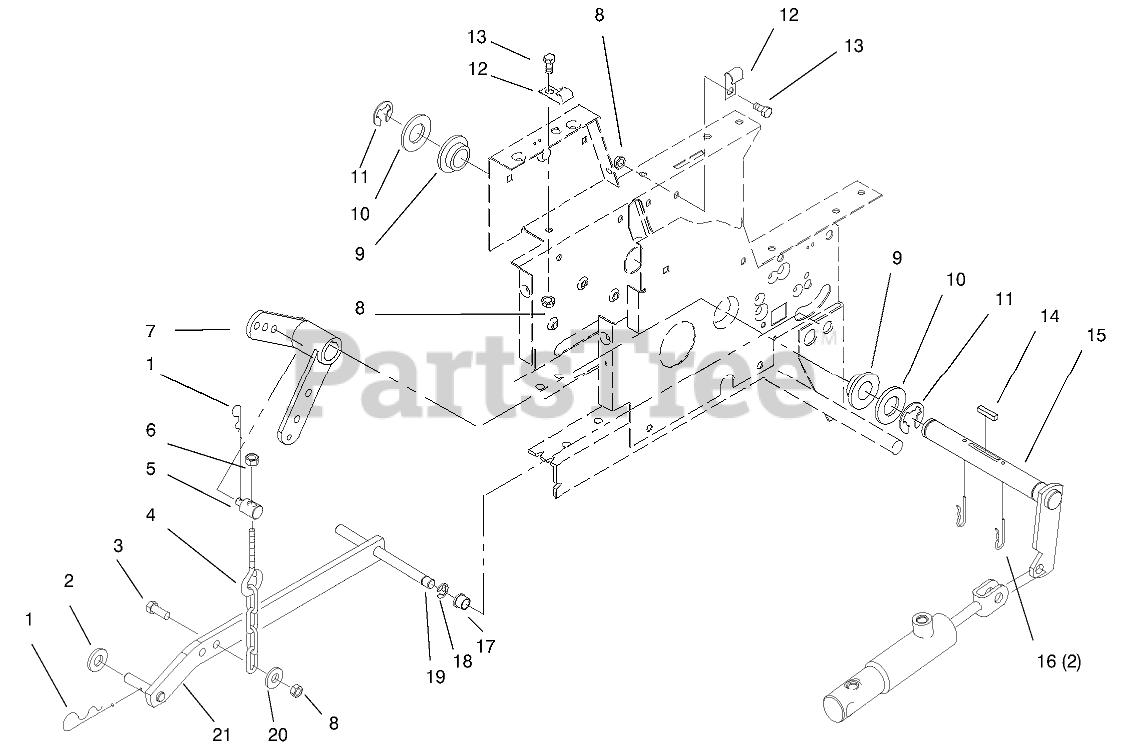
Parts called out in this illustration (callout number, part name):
1	PIN-HAIR
2	WASHER-FLAT
3	SCREW-HH
4	CHAIN-LIFT
5	TRUNNION-LIFT
6	NUT-LOCK, NI
7	LIFT LEVER ASM
8	NUT-LOCK, NI
9	BEARING-FLANGE
10	WASHER-FLAT
11	RING-RETAINING
12	CLIP
13	SCREW-HH
14	KEY-SQUARE
15	WLDMT-LIFT ARM
16	PIN-HAIR
17	BUSHING
18	RING-RETAINING, EXTERNAL
20	WASHER-PLAIN
21	Bar-Lift
